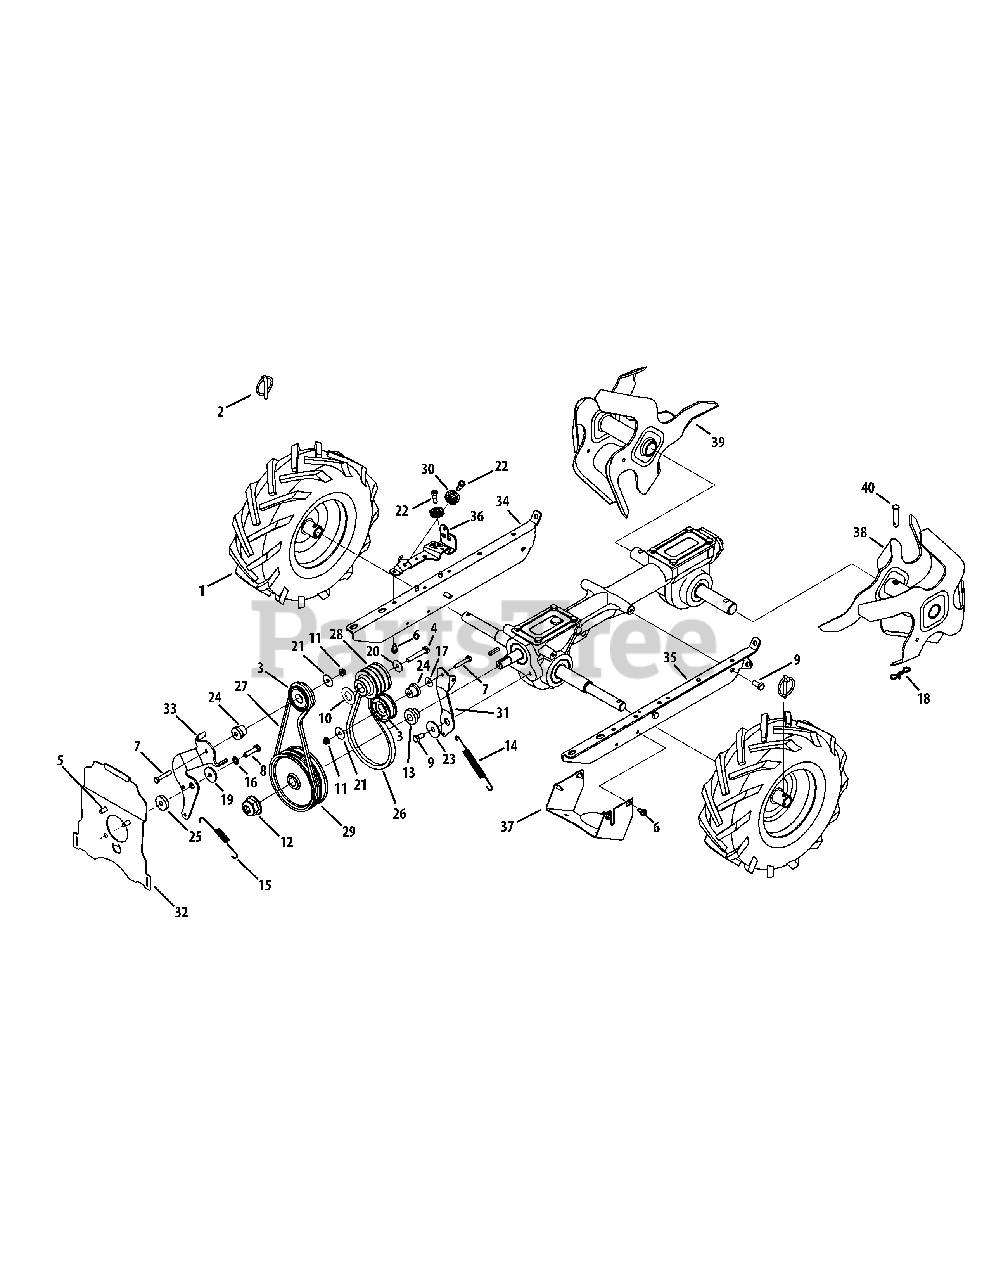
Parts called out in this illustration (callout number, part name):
1	Complete Wheel Assembly, 13 x 5 x 6 (B, C)
2	Klik Pin
3	Idler Pulley Assembly
4	Hex Head Screw, 3/8-24 x 2.25
5	Hex Head Screw, 5/16-24 x .625
6	Self Tapping Screw, 1/4-20 x .500
7	Hex Head Screw, 1/4-20 x 1.50
8	Hex Head Screw, 5/16-18 x 1.25
9	Hex Head Screw, 5/16-18 x .75, Patch
10	Washer, Flat, .760 x 1.50 x .120
11	Nylon Hex Lock Nut, 1/4-20
12	Nut, 9/16-18, Flange Lock
13	Hub, 5/8 Spline
14	Extension Spring, .480 OD X 5.00 LG
15	Extension Spring
16	Lock Washer, 5/16
17	Washer, .28 x .74 x .063
18	Cotter Pin, Bow Tie
19	Flat Washer, .330 X 1.25 X .120
20	Bell Washer, .396 x 1.140 x .095
21	Flat Washer, .265 x 1.0 x .030
22	Shoulder Screw, .342 x .335 1/4-28
23	Pivot Idler Spacer
24	Shoulder Spacer, .260 x .785 x .538
25	Pivot Idler Spacer
26	V-Belt, 4L x 25.375 Long
27	V-Belt, 3L x 29.125 Long
28	Engine Pulley
29	Transmission Pulley
30	Cable Roller
31	Idler Bracket, Forward
32	Cover Plate
33	Idler Bracket, Reverse
34	Mounting Frame, RH
35	Mounting Frame, LH
36	Pulley Bracket
37	Pulley Shield
38	Tine Assembly, LH
39	Tine Assembly, RH
40	Clevis Pin, .375 x 1.75
